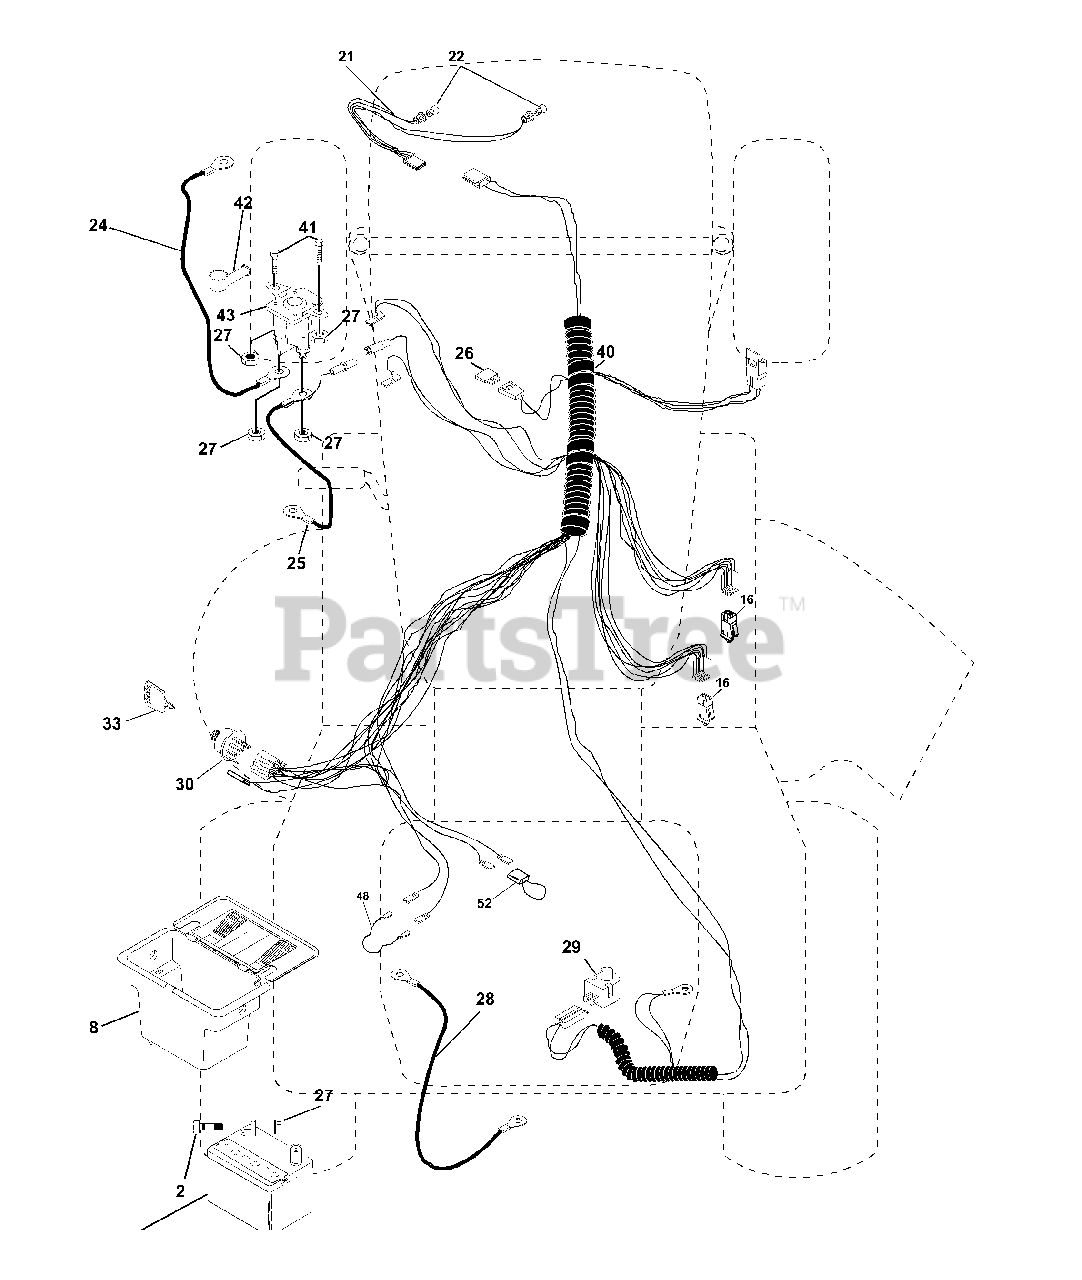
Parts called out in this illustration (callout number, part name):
1	Battery 12 Volt 25 Amp
2	Bolt, Hex Head 1/4-20 unc x 3/4
8	Case, Battery Mech Hinge
16	Switch, Interlock Push-In
21	Harness, Light Socket
22	Bulb, Light
24	Cable, Battery, 6 Gauge, Red, 11"
25	Cable, Battery, 6 Gauge, Red, W/16 Wire
26	Fuse
27	Nut Keps Hex 1/4-20 UNC
28	Cable, Ground, 6 Gauge, Black, 12"
29	Switch, Plunger
30	Switch, Ignition
33	Key, Ignition
40	Harness, Ignition
41	Bolt, Hex Head, Fin. 1/4-20 x 1/2
42	Cover, Terminal, Red
43	Solenoid
48	Adaptor Ammeter Rectangular
52	Protection Wire Loop
